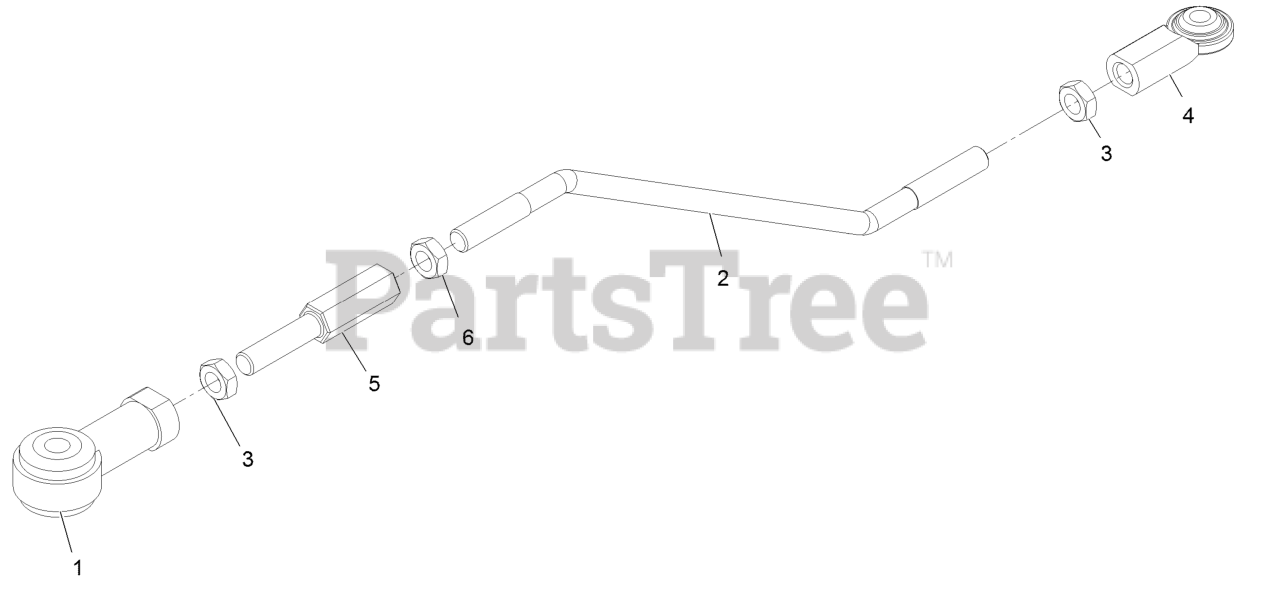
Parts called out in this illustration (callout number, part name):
1	End-Rod, Isolated
2	Rod-Linkage, Rear
3	Nut-Jam 3/8-24
4	Balljoint
5	Rod-Adjustment
6	Nut-Jam 3/8-24 LH
